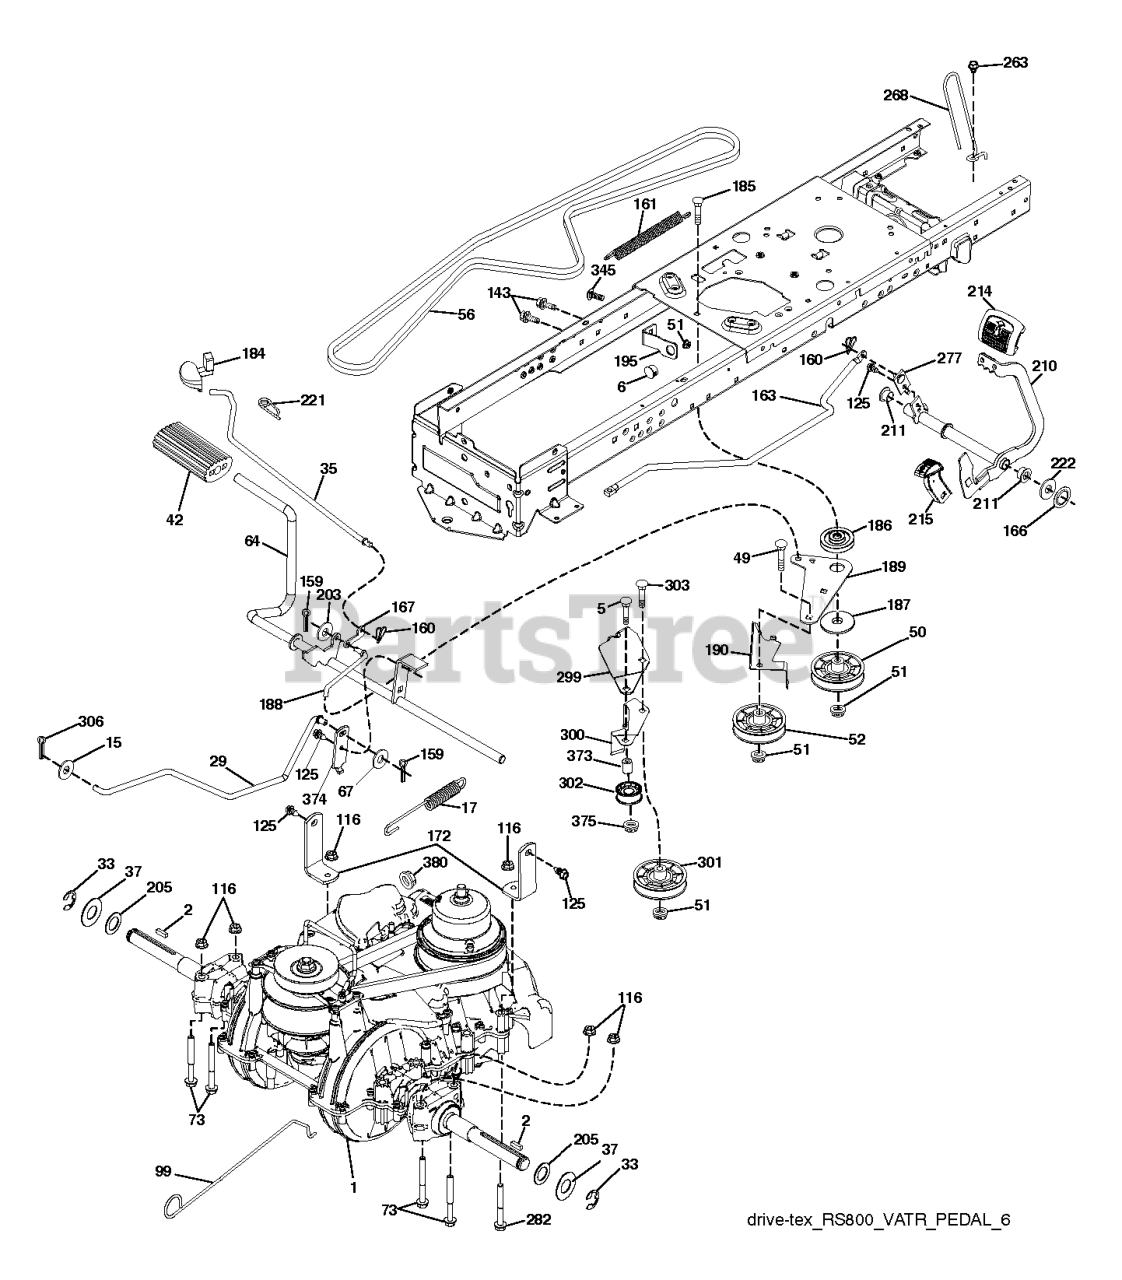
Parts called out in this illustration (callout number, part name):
2	SQUARE KEY
6	BUSHING.SNAP.NYL.BLK.
15	WASHER
17	SPRING BRAKE VARIATOR
29	BRAKE.VARIATOR.SD3
35	ROD.CNTRL.PARK.PREDATOR.LT.TEX
37	WASHER.HARDENED
42	PEDAL COVER T
49	BOLT
50	IDLER.FLAT.910.OFFSET
51	NUT LOCK FLG 3/8-16 UNC
52	IDLER.V-GROOVE.910.OFFSET
56	BELT.V.EURO.VARIATOR
64	SUBASM.SHAFT.PEDAL.BRAKE
67	WASHER
73	BOLT
99	ROD.BYPASS.VARIATOR.GEN2
116	NUT LOCK HEX FLANGE 5/16-18
125	SCREW
143	SCREW LT
159	COTTER PIN
160	RETAINER CLIP
161	SPRING, RETURN LT
163	ROD.CONTROL.PEDAL.VARIATOR
166	NUT.PUSH.625
167	LATCH.BRAKE.SPRING
172	STRAP.TORQUE.VARIATOR
184	HANDLE.PARKNG BRK.PRED.LT.428
186	SPACER.RETAINER
187	WASHER 12/32X2X10GA
188	RP.LINK.CLUTCH.GROUND.DRIVE
189	BELLCRANK.GROUND.DRIVE.TEX.
190	KEEPER.BELLCRANK.DRIVE
195	BRACKET.BRAKE.BRAKE.VAR.SD
203	WASHER
210	WELDMENT.PEDAL.VARIATOR
211	BEARING.NYLON
214	PEDAL.FORWARD.PAD.TEX
215	CAP.PEDAL.REVERSE.VARIATOR
221	RETAINER.SPRING.CLIP.H
222	WASHER 21/32 X 1-1/4 X 10 GA.
263	SCREW, 3/8-16X3/4
268	GUARD MUFFLER
275	WASHER
277	SUBASM.LINK.ROCKER.PEDAL
282	BOLT HEX FLGHD 5/16-18X3 GR. 5
299	BRACKET.MOUNT.IDLERS
300	KEEPER.IDLERS.REAR.VARIATOR
301	PULLEY.IDLER.V-GROOVE
302	PULLEY.IDLER.FLAT.2"
303	BOLT CARRIAGE
306	PIN COTTER
345	BOLT
373	SPACER.IDLER
374	ARM.CONTROL.BRAKE
375	LOCKNUT
378	NUT.PUSH.8MM
